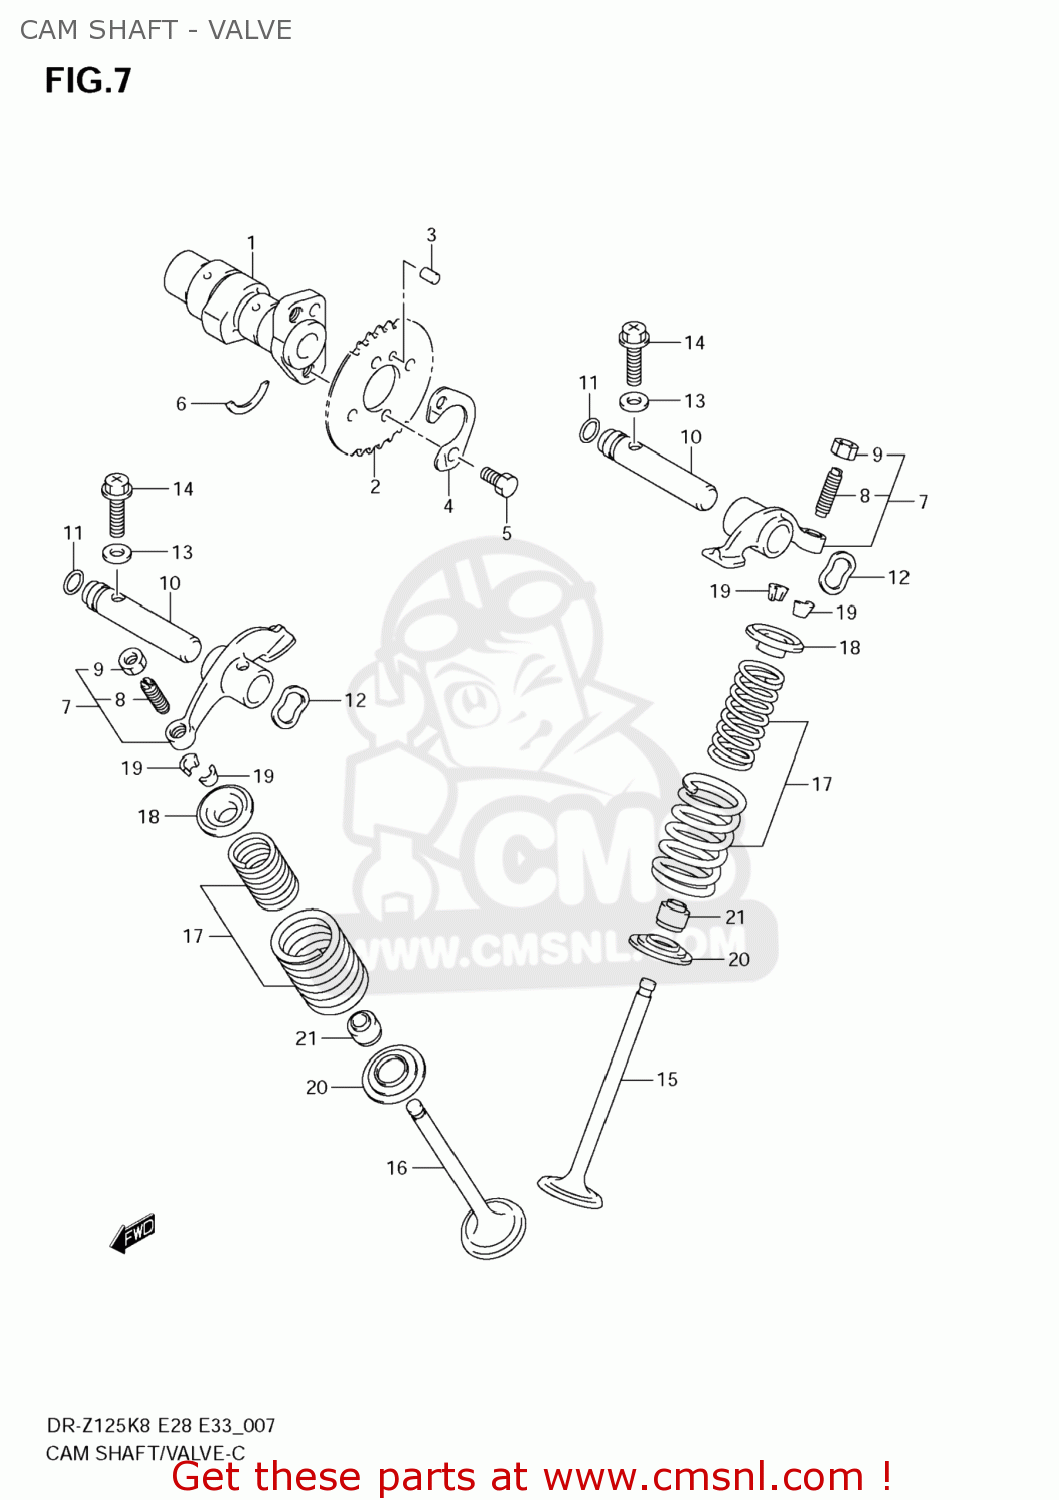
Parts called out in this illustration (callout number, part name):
1	CAMSHAFT
2	SPROCKET,CAMSHAFT
3	PIN(5X8)
4	WASHER,SPROCKET
5	BOLT(6X10.5)
6	C RING
7	ARM ASSY,VALVE ROCKER
8	SCREW,TAPPET ADJUSTING
9	NUT,ADJUSTING SCREW
10	SHAFT,VALVE ROCKET
11	O RING(D:1.9,ID:8.6)
12	WASHER
13	GASKET(5.8X13X1.2) (NAS)
14	SCREW
15	VALVE,INTAKE
16	VALVE,EXHAUST
17	SPRING SET,VALVE
18	RETAINER,VALVE SPRING
19	COTTER,VALVE
20	SEAT,VALVE SPRING
21	SEAL,OIL(5.5X11X8.2)
